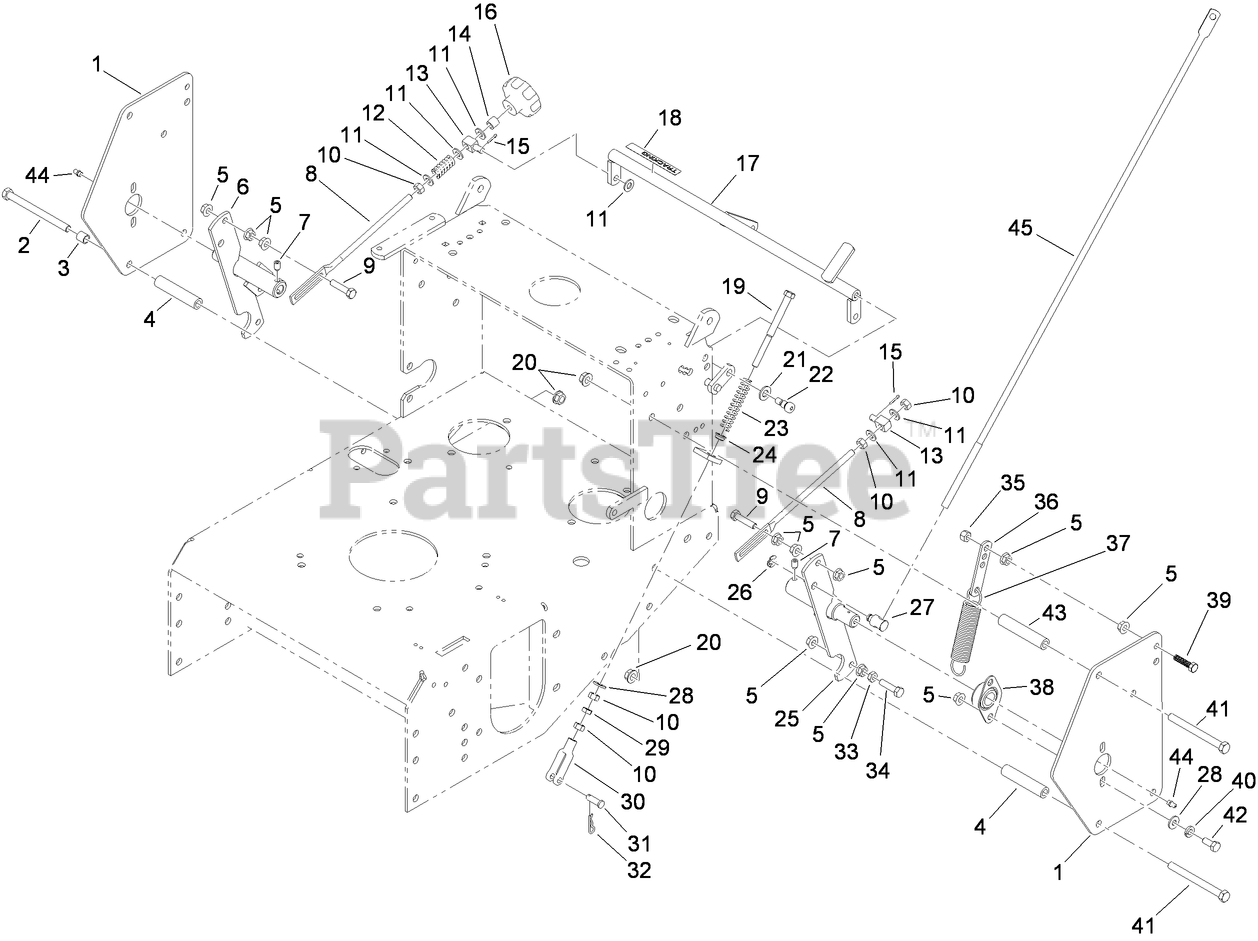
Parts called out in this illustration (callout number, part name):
1	SHIELD-CONTROL
2	SCREW-HH
3	SPACER-SHORT
4	SPACER-SHIELD
5	NUT-HF
6	SHAFT-CONTROL, RH
7	SCREW-SET
8	LINK-CONTROL, SPEED
9	SCREW-HH
10	NUT-HEX
11	WASHER-PLAIN
12	SPRING-COMPRESSION
13	SWIVEL-ADJUSTABLE, SHORT
14	SPACER
15	PIN-COTTER
16	KNOB-TRACKING
17	Crank-Control, Speed
18	DECAL-TRACKING
19	BOLT-RETURN, NEUTRAL
20	NUT-HHF, WHIZ
21	WASHER-FLAT
22	SCREW-HSH
23	SPRING-RETURN, NEUTRAL
24	BUSHING-NYLON, FLANGED
25	Shaft-Control, LH
26	RING-RETAINING
27	SWIVEL-LEVER, DRIVE
28	WASHER-FLAT
29	NUT-JAM
30	YOKE-ADJUSTABLE
31	PIN-CLEVIS
32	PIN-COTTER
33	NUT-JAM
34	SCREW-HH
35	NUT-LOCK, NI
36	TAB-SPRING, EXTENSION
37	SPRING-EXTENSION
38	BEARING-FLANGE, SIDE
39	BOLT-TAP, HH
40	WASHER-LOCK
41	SCREW-HH
42	SCREW-HH
43	Spacer-Shield
44	FITTING-GREASE
45	ROD-LEVER, DRIVE
